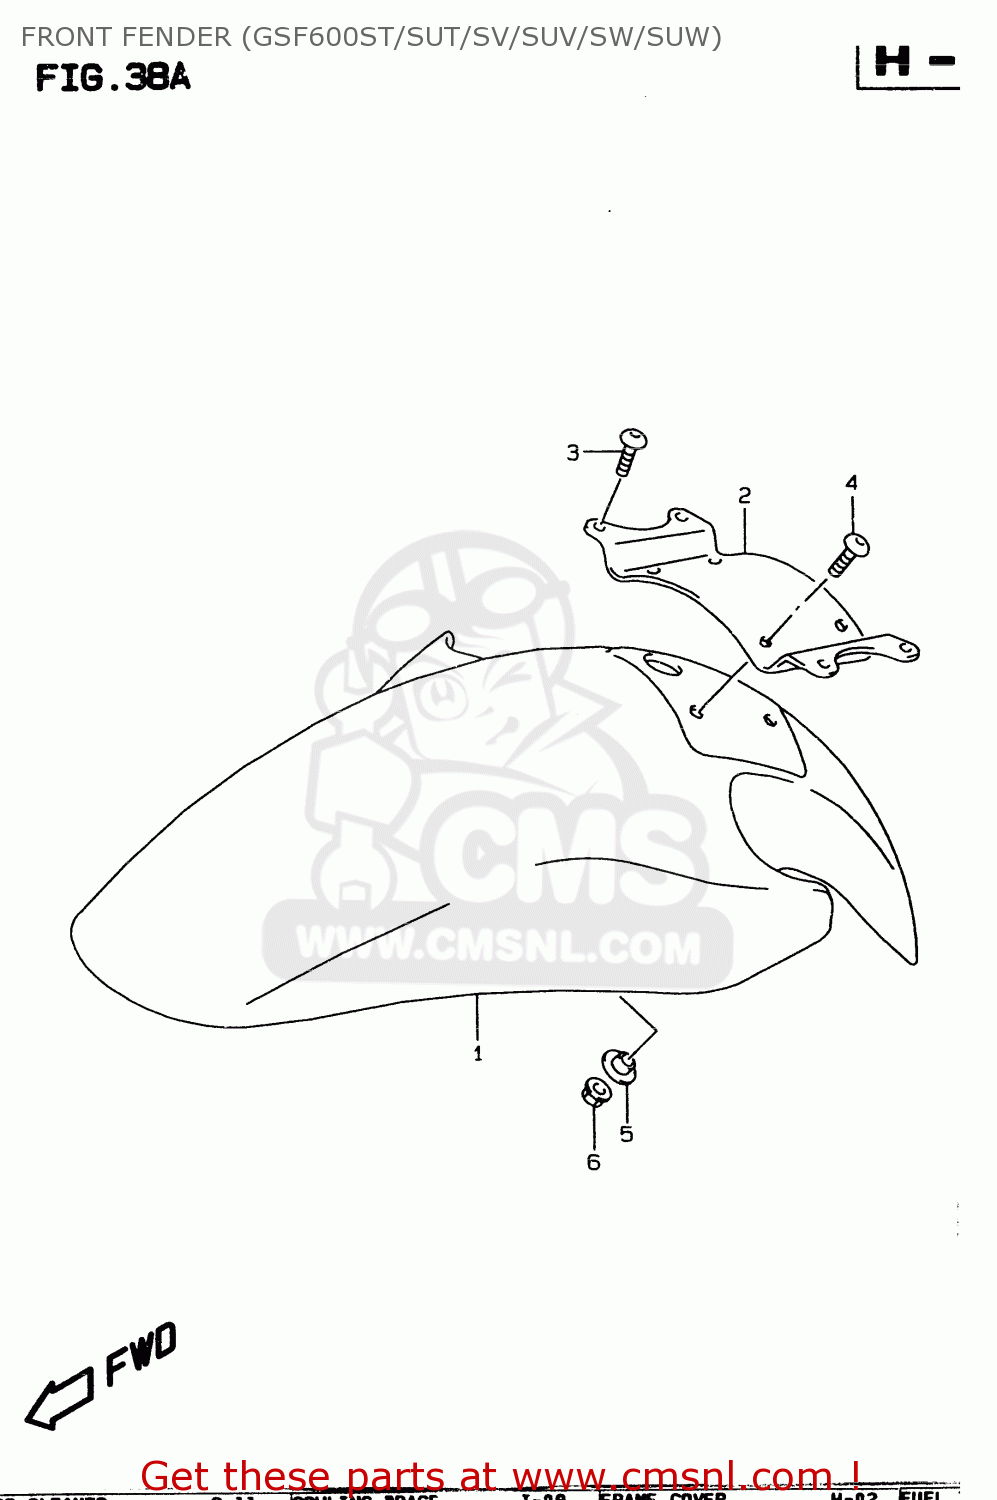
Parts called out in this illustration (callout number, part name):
1	FENDER SET,FR
2	BRACE,FR FENDER
3	SCREW(6X12)
4	SCREW(5X16)
5	WASHER
6	NUT
